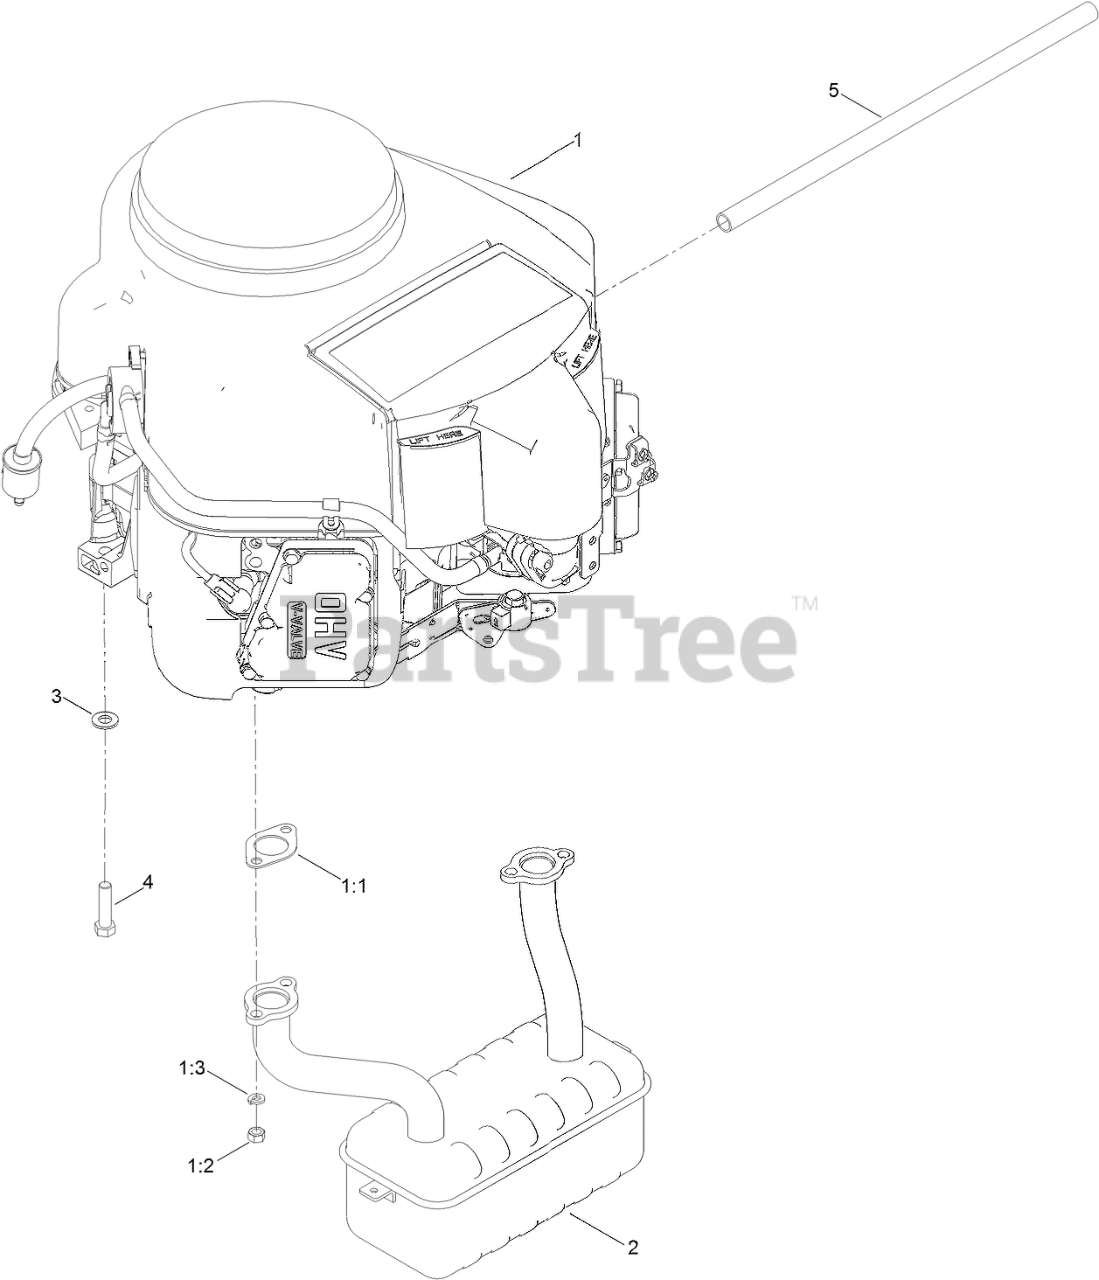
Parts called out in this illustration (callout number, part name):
1:1	GASKET-EXHAUST
1:3	WASHER-LOCK
2	MUFFLER
3	WASHER-FLAT
4	BOLT-HH
5	TUBE-DRAIN, OIL
